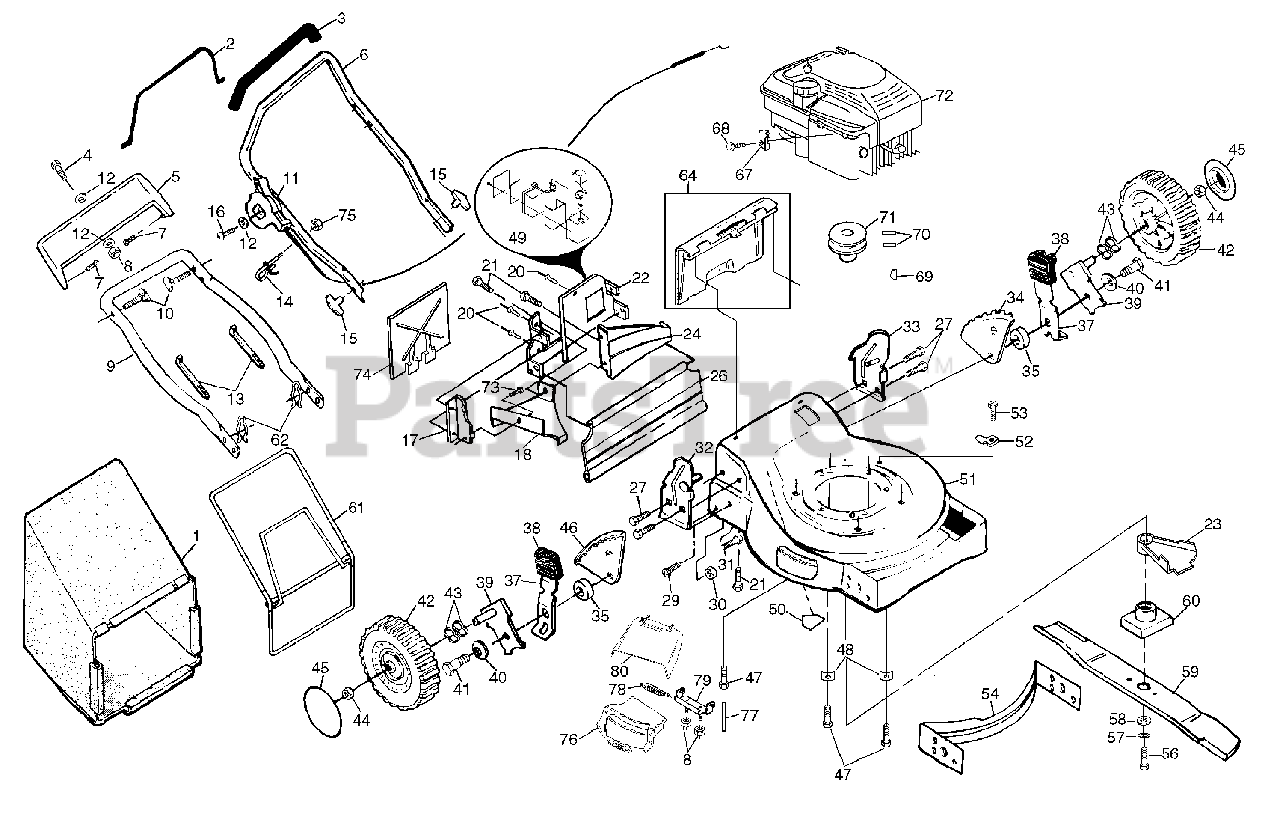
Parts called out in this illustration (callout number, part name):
1	Grass Bag Assembly
2	Control Bar
3	Handle Grip
4	Hex Washer Head Machine Screw 1/4-20 x 1-1/2
5	Trim Plate
6	Upper Handle
7	Self-tapping Screw #10-24 x 5/8
8	Locknut 1/4-20
9	Lower Handle
10	Handle Bolt
11	Throttle Control
13	Wire Tie
14	Rope Guide
15	Handle Knob
16	Round Head Screw 1/4-20 x 2-3/4
17	Side Baffle
18	Discharge Baffle
21	Hex Tapping Screw 1/4-20 x 1/2
22	Back Plate
23	Debris Shield
24	Rear Baffle
26	Rear Skirt
27	Thread Cutting Screw 5/16-18 x 3/4
29	Hinge Screw
30	Locknut
32	Handle Bracket Assembly (Right)
33	Handle Bracket Assembly (Left)
34	Wheel Adjusting Bracket (Left)
35	Spacer
37	Selector Spring
38	Selector Knob
39	Axle Arm Assembly
40	Belleville Washer
41	Shoulder Bolt 3/8-16
42	Wheel & Tire Assembly
43	Wave Washer
44	Nut
46	Wheel Adjusting Bracket (Right)
47	Thread Rolling Screw 3/8-16 x 1
48	Engine Washer
49	Battery
50	Danger Decal
51	Lawn Mower Housing
52	Guide Clip (Housing)
53	Hex Washer Head Screw #10-24 x 1/2
54	Front Baffle
56	Hex Head Screw 3/8-24 x 1-3/8 Gr. 8
57	Helical Lockwasher 3/8
58	Hardened Washer
60	Blade Adapter
61	Catcher Frame Assembly
62	Hairpin Cotter
64	Rear Door Assembly
67	Cable Clamp
68	Thread Rolling Screw #10-32 x 5/8
69	Hi-Pro Key
70	Set Screw 1/4-20 x 5/16
71	Engine Pulley
74	Mulcher Plate
75	Keps Locknut
76	Mulcher Door
78	Hinge Spring
79	Hinge Bracket W/Fin
80	Discharge Deflector
